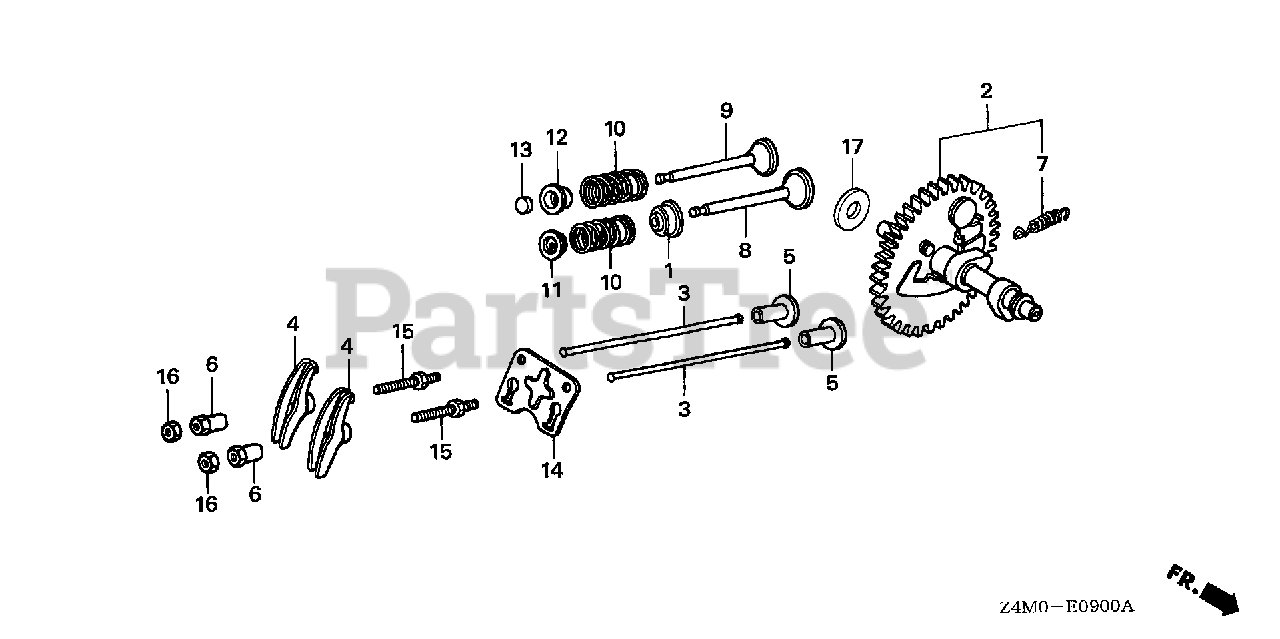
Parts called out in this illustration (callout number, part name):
1	SEAL, VALVE STEM
2	CAMSHAFT ASSY.
3	ROD, PUSH
4	ARM, VALVE ROCKER
5	LIFTER, VALVE
6	PIVOT, ROCKER ARM
7	SPRING, WEIGHT RETURN
8	VALVE, IN.
9	VALVE, EX.
10	SPRING, VALVE
11	RETAINER, IN. VALVE SPRING
11	RETAINER, VALVE SPRING (EXHAUST SIDE)
12	RETAINER, EX. VALVE SPRING
12	RETAINER
13	ROTATOR, VALVE
14	PLATE, PUSH ROD GUIDE
15	BOLT, PIVOT (8MM)
16	NUT, PIVOT ADJ.
17	WASHER, THRUST (14.1MM)
